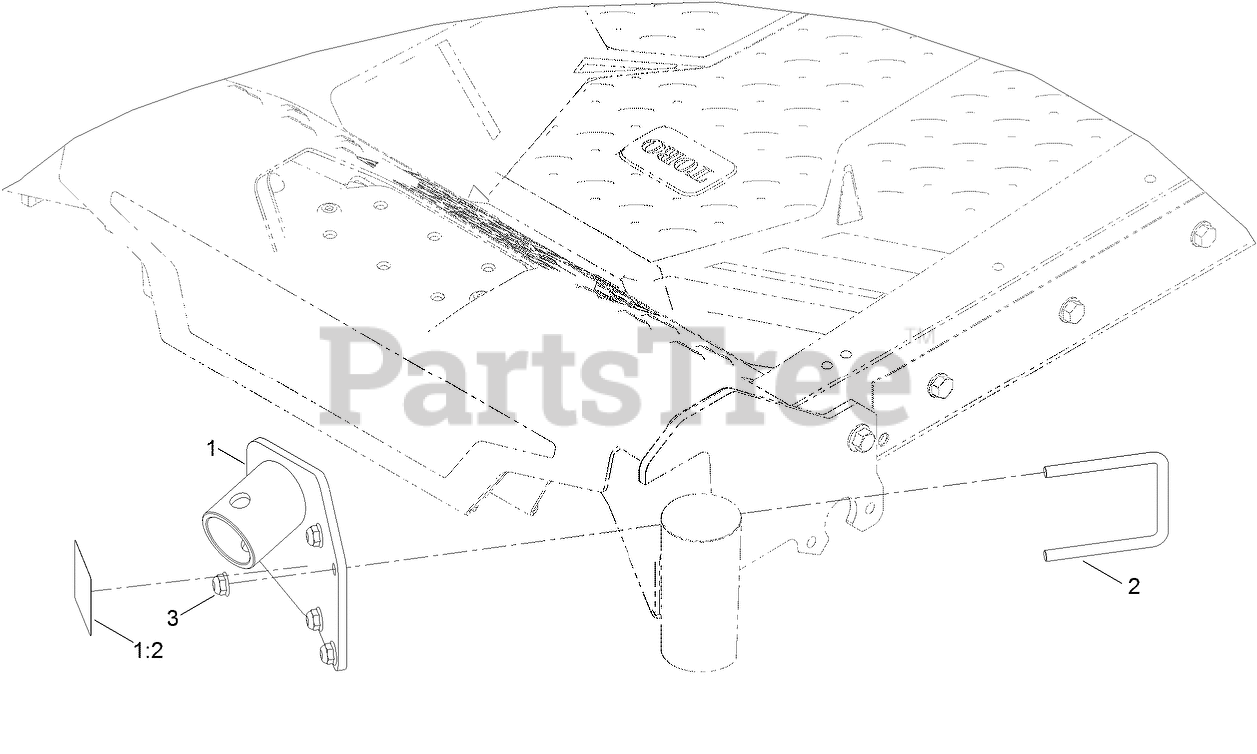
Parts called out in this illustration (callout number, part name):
1	JACK MOUNT ASM
1:2	DECAL-WARNING, JACK
2	U-BOLT
3	NUT-HF
